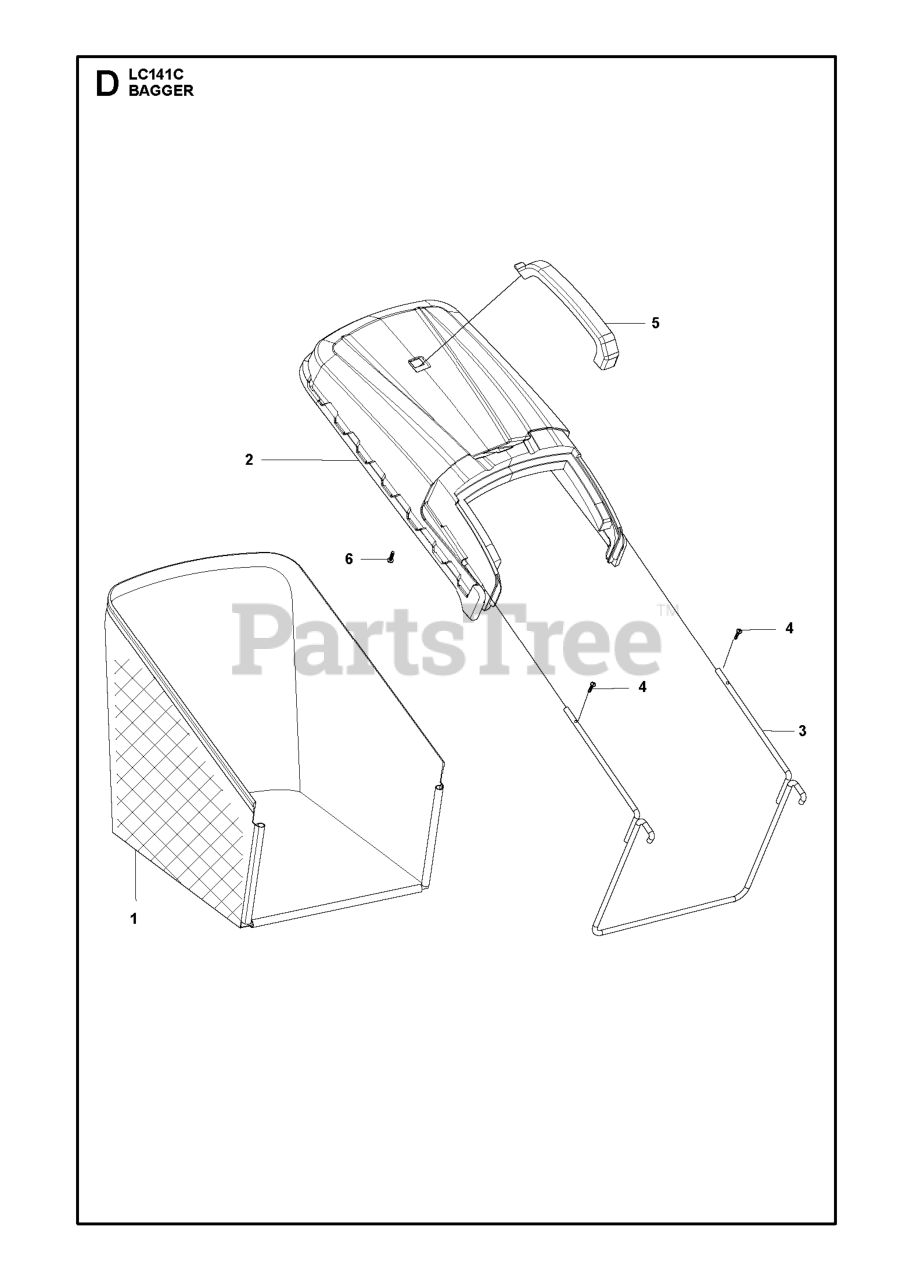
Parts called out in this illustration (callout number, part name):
1	GRASSBAG #25100173001
2	COVER GRASS CATCHER #253417001
3	BRACKET #26300299201
5	HANDLE #25341800101
6	SCREW ST4.8*19,GB845 #26800104
